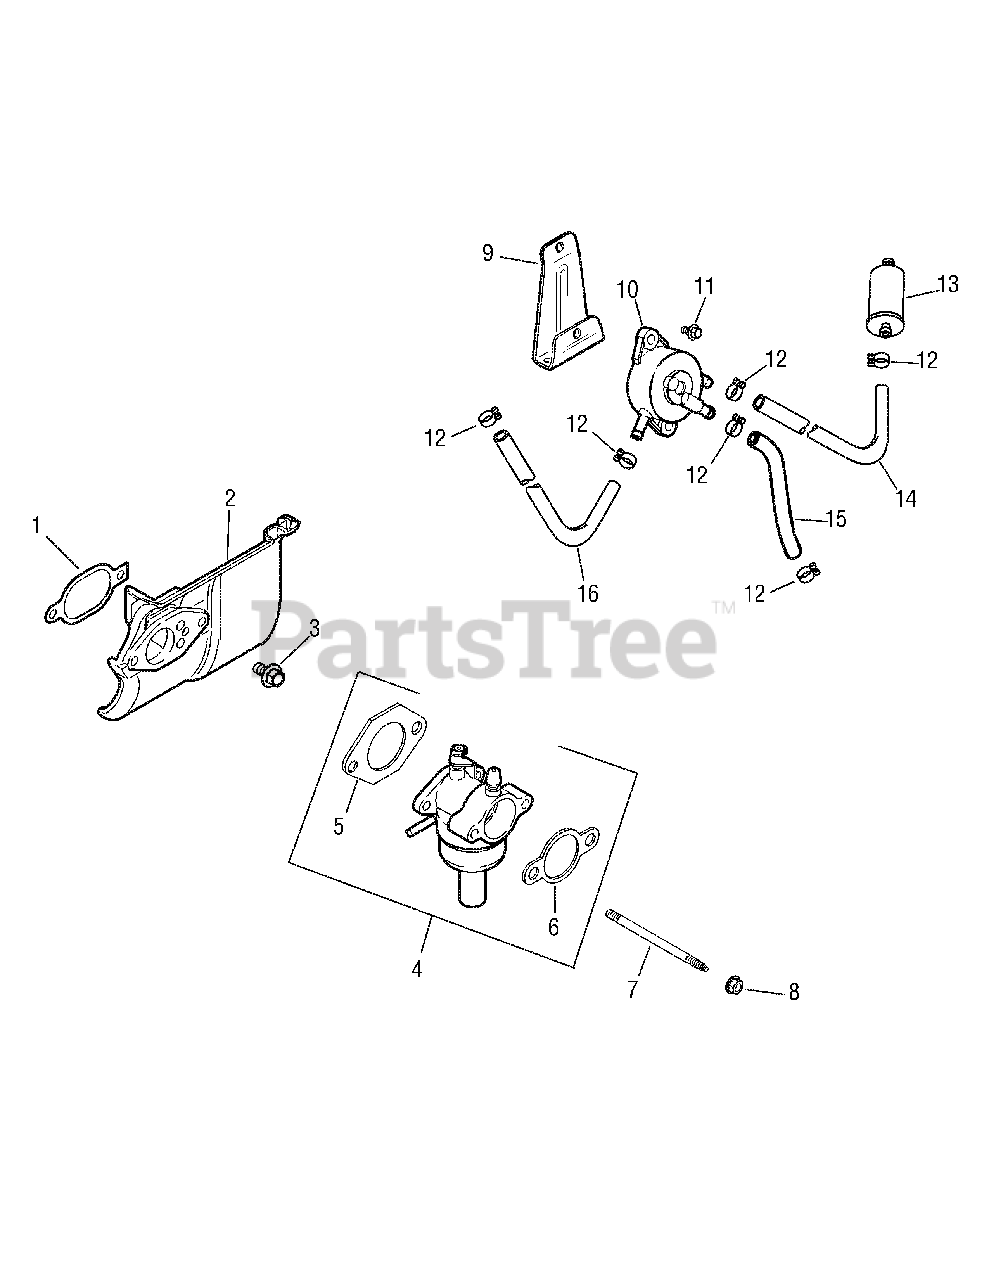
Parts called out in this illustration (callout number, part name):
1	Gasket, heat deflector
2	Deflector, heat
3	Screw, hex. flange M6x1.0x20
4	Carburetor w/gaskets (Includes 5,6)
5	Gasket, carburetor
6	Gasket, air cleaner
7	Stud, carburetor mounting
8	Nut, hex. flange M6x1.0
9	Bracket, fuel pump mounting
11	Screw, hex. flange
12	Clamp, hose
13	Filter, fuel
14	Line, fuel 15-3/4" (pump to filter)
15	Line, fuel 2" (pump to carb)
16	Line, fuel 10" (pump to fitting)
